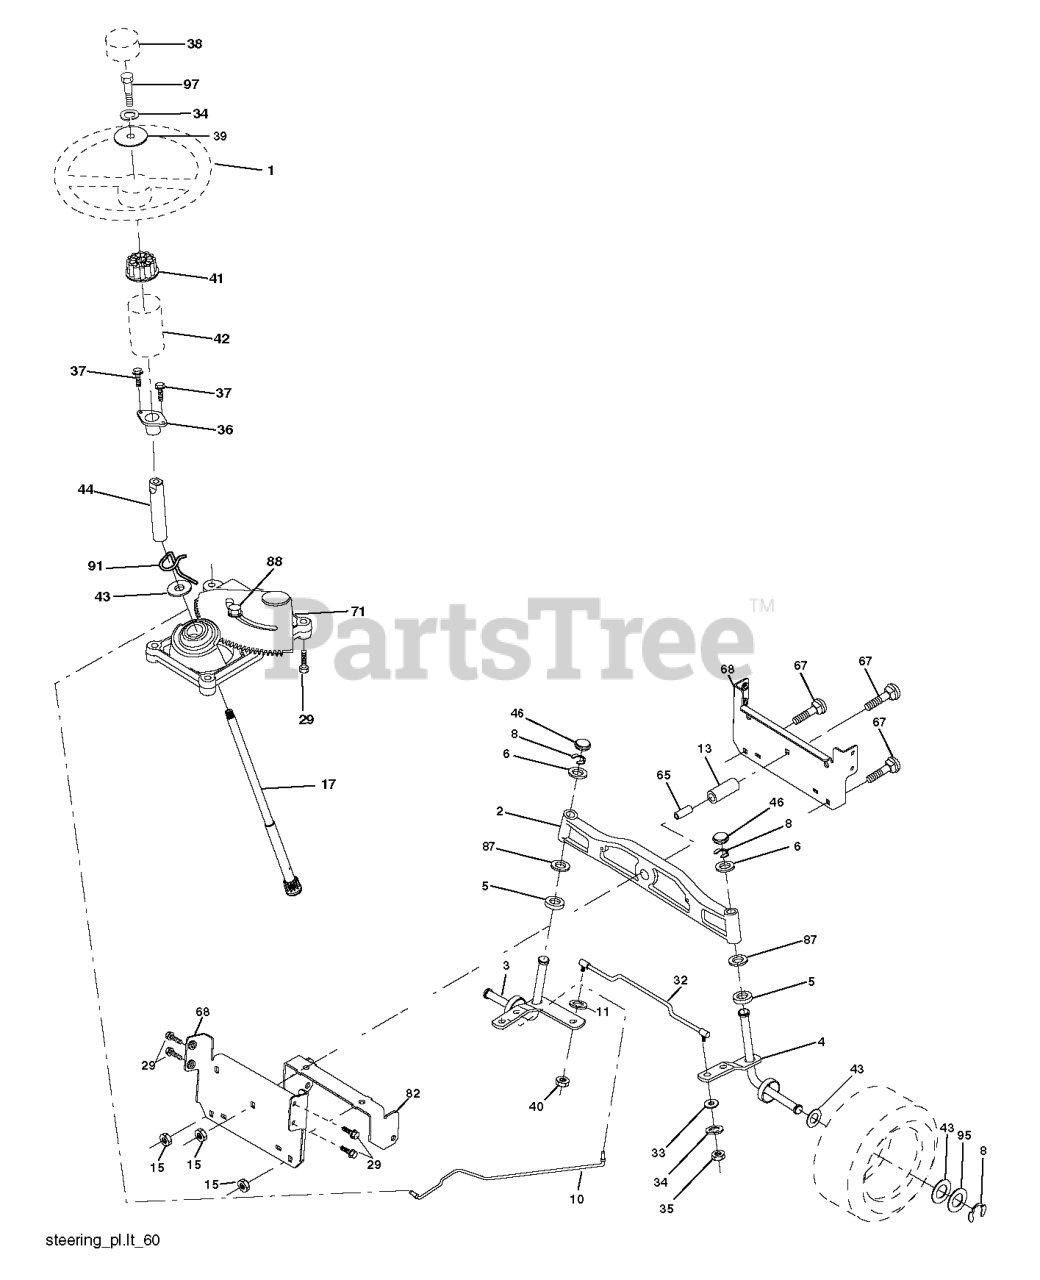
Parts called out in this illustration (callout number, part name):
1	STEERING WHEEL
2	AXLE ASSY FRONT
3	SPINDLE.ASM.LH.15"TIRES
4	SPINDLE.ASM.RH.15"TIRES
5	THRUST WASHER
9	BRNG T
10	DRAGLINK.15".TIRES.2001
11	WASHER, LOCK 3/8
13	TUBE, PIVOT AXLE
15	NUT
17	SHAFT STEERING SPLINE
29	SCREW, 3/8-16X3/4
33	WASHER M
34	WASHER.LOCK.HVY.HLCL.SPR.5/16
35	NUT, CROWNLOCK
36	BUSHING, STEERING
37	SCREW.TT.#10-32X.5.3/8.FLANGE
38	INSERT.CAP.STRG.WH.GRAY
39	WASHER.11/32
40	NUT CROWNLOCK 3/8-24
41	ADAPTER, WHEEL STNG..
42	BOOT STEERING
44	SHAFT.EXTEN.STRG.SPLINE
46	CAP.SPINDLE.BLACK
65	SPACER BRACE AXLE
67	BOLT CARRIAGE
68	BRACE.AXLE.15"TIRES
71	STEERING ASM
82	BRACKET.SUSP.CHASSIS.FRONT.15
87	WASHER, FLAT .781 X 1 1/2"
88	BOLT, SHOULDER 7/16-20
91	CLIP.STEERING
95	WASHER.HARDENED
